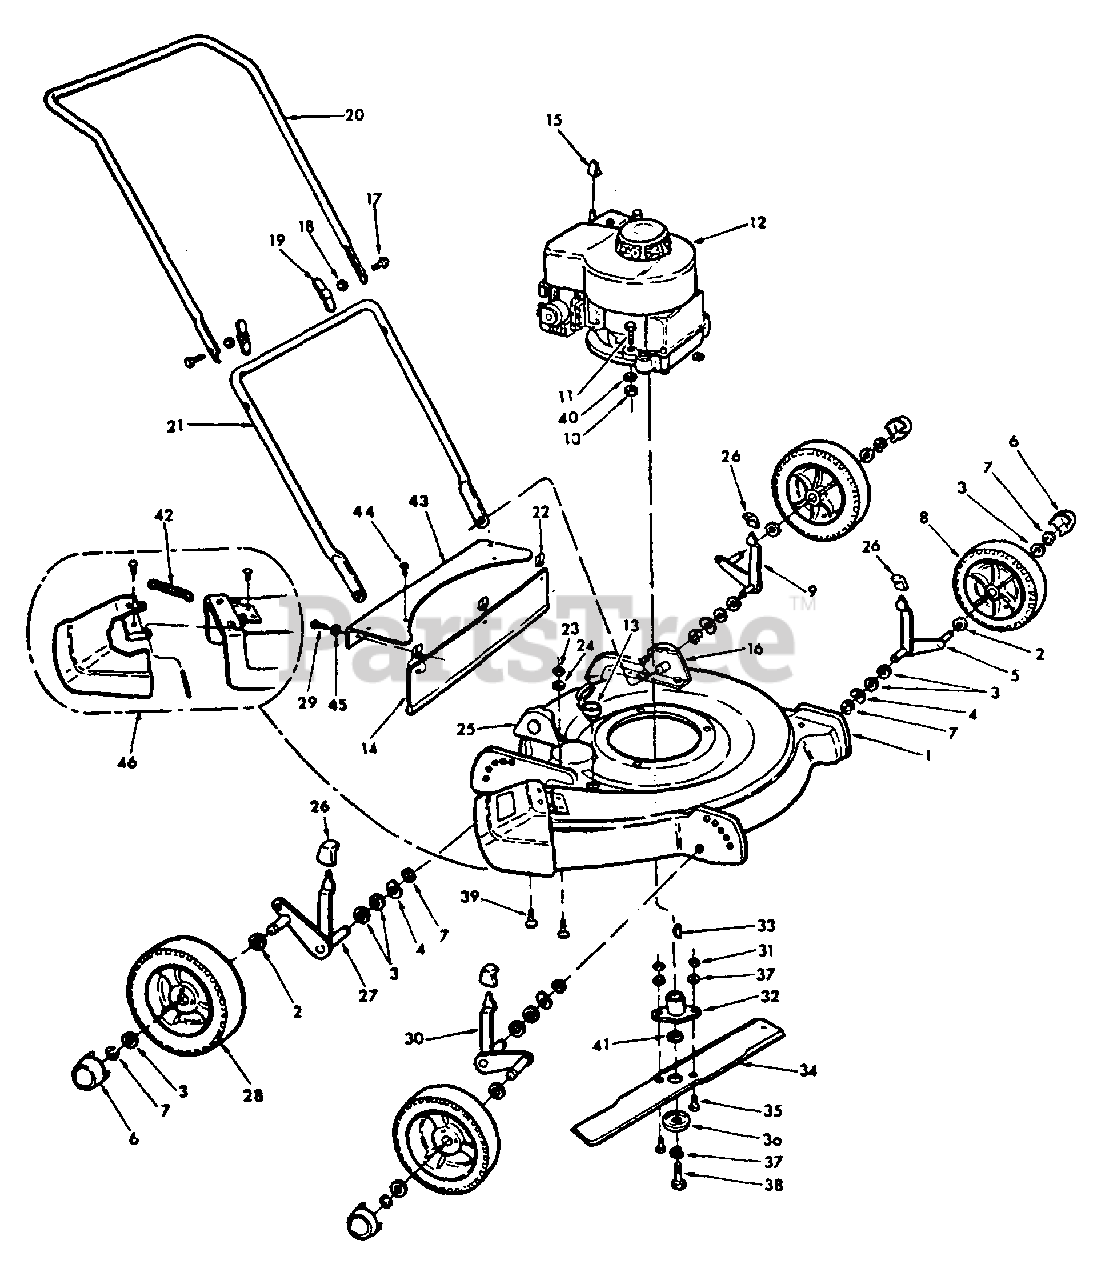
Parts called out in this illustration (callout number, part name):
1	HOUSING, BLADE
2	WASHER, 1/2 X 1 X .125
3	WASHER, 1/2 X 1 X .030
4	WASHER, WAVE
5	AXLE, FRONT LH
7	RING, RETAINING
8	WHEEL AND TIRE ASSY, FRONT
9	AXLE, REAR LH
10	NUT, 5/16-18 ZND HEX.
11	SCREW, 5/16-18 X 1-1/2 ZND HEX-HD CAP
12	ENGINE, HP
13	CAP, WASHOUT PORT
14	DEFLECTOR, REAR
15	KNOB, THROTTLE
16	BRACKET AND PIN ASSY, LH
17	SCREW, 5/16-18 X 1-3/4
18	WASHER, 5/16 REG LOCK
19	NUT, 5/16-18 ZND WING
20	HANDLE, UPPER
21	HANDLE, LOWER
22	NUT, SHAPED SPRING
23	NUT, 1/4-20 PHC HEX. LOCK
24	WASHER, 4 REG LOCK
25	BRACKET AND PIN ASSY, RH
26	KNOB, ADJUST LEVER
27	AXLE, REAR RH
28	WHEEL AND TIRE ASSY, REAR
29	SCREW, 10-12 X 7/8 SHEET METAL
30	AXLE, FRONT RH
31	NUT, 1/4-20 HEX.
32	ADAPTER, BLADE
33	KEY, WOODRUFF - ENGINE CRANK
34	BLADE, 20 IN.
35	SCREW, 1/4-20 X 3/4 HEX-HD CAP
36	WASHER, BLADE TO CRANKSHAFT
37	WASHER, 3/8 REG LOCK
38	SCREW 3/8-24 X 1-1/8 HEX-HD CAP
39	SCREW, 1/4-20 X 5/8 SQ-NK CRG
40	WASHER, .344 X .625 X .054 ZND
41	SPACER, ANTI FLIP BRACKET
42	SPRING, DEFLECTOR
43	COVER, DECK
44	SCREW, 10-24 X 1/2 HEX WASHER-HD TAP
45	WASHER, .219 X .75 X .054
46	DEFLECTOR ASSY, MISSILE
